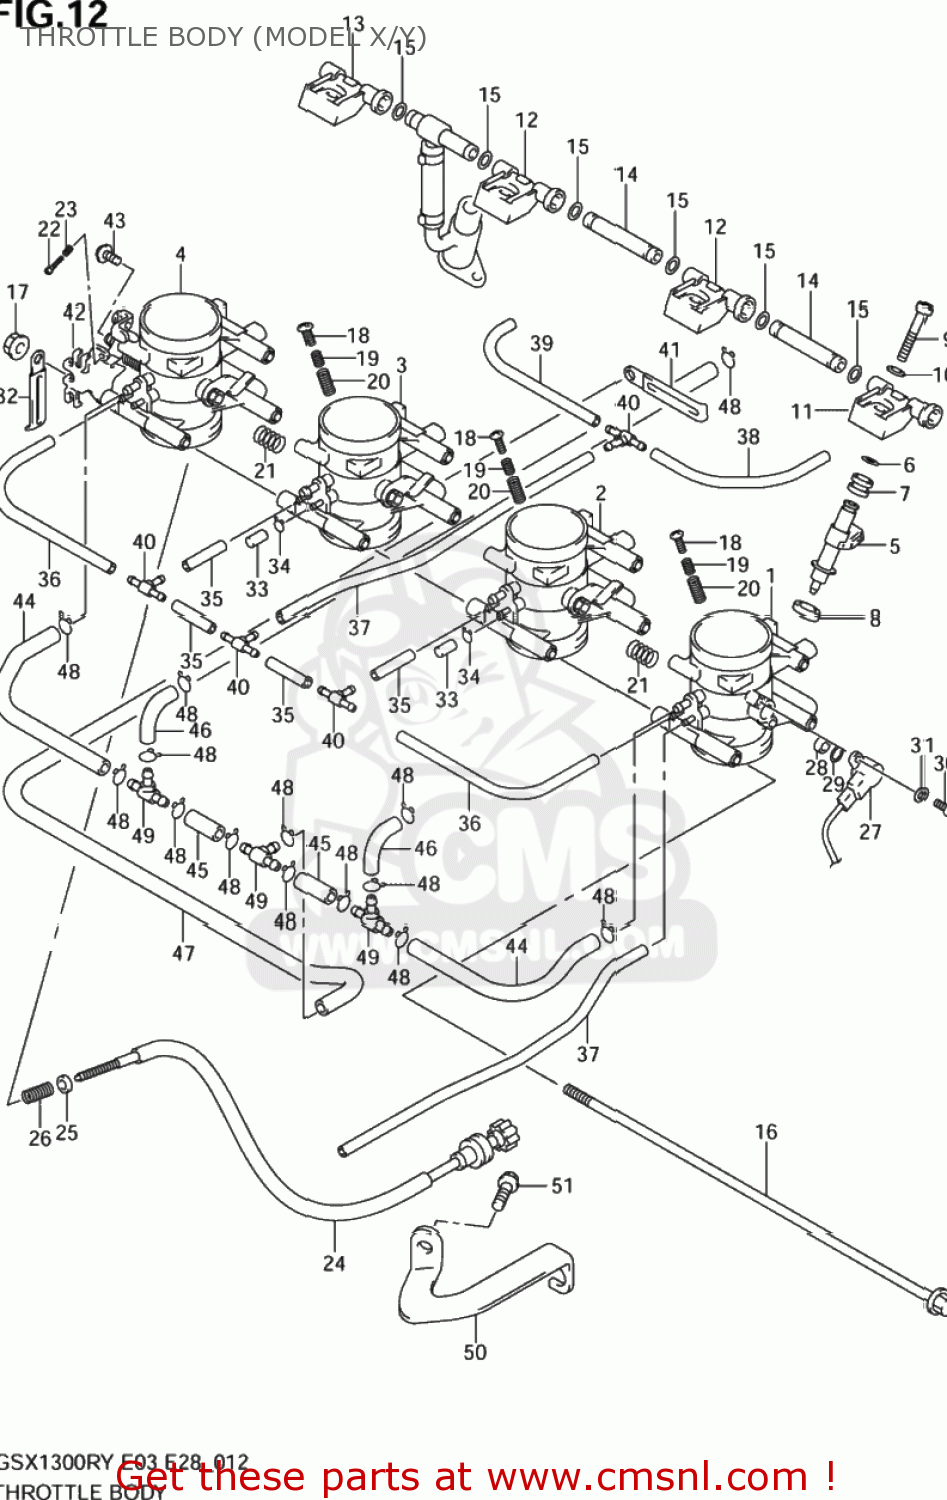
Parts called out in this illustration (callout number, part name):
1	THROTTLE BODY ASSY,L
2	THROTTLE BODY ASSY ML
3	THROTTLE BODY ASSY MR
4	THROTTLE BODY ASSY,R
5	INJECTOR ASSY
6	O RING
7	RING,CUSHION
8	RING,SEAL
9	SCREW
10	WASHER
11	JOINT NO.1
12	JOINT NO.2,3
13	JOINT NO.4
14	JOINT
15	O RING
16	BOLT
17	NUT
18	SCREW
19	SPRING
20	SPRING
21	SPRING
22	SCREW
23	SPRING
24	SCREW,STOP
25	WASHER
26	SPRING
27	SENSOR ASSY,THROTTLE
28	COLLAR
29	O RING
30	SCREW
31	WASHER
32	CLAMP
33	CAP,RUBBER
34	CLIP
35	HOSE,RUBBER(L:35)
36	HOSE,RUBBER(L:100)
37	HOSE,RUBBER(L:200)
38	HOSE,RUBBER(L:120)
39	HOSE,RUBBER(L:110+20)
40	JOINT
41	CLAMP
42	PLATE,STAY
43	SCREW
44	HOSE,RUBBER(L:80+25)
45	HOSE,RUBBER(L:35)
46	HOSE,RUBBER(L:30+30)
47	HOSE,RUBBER(L:440+30)
48	CLIP
49	JOINT
50	PLATE,IDLE ADJUST
51	BOLT
